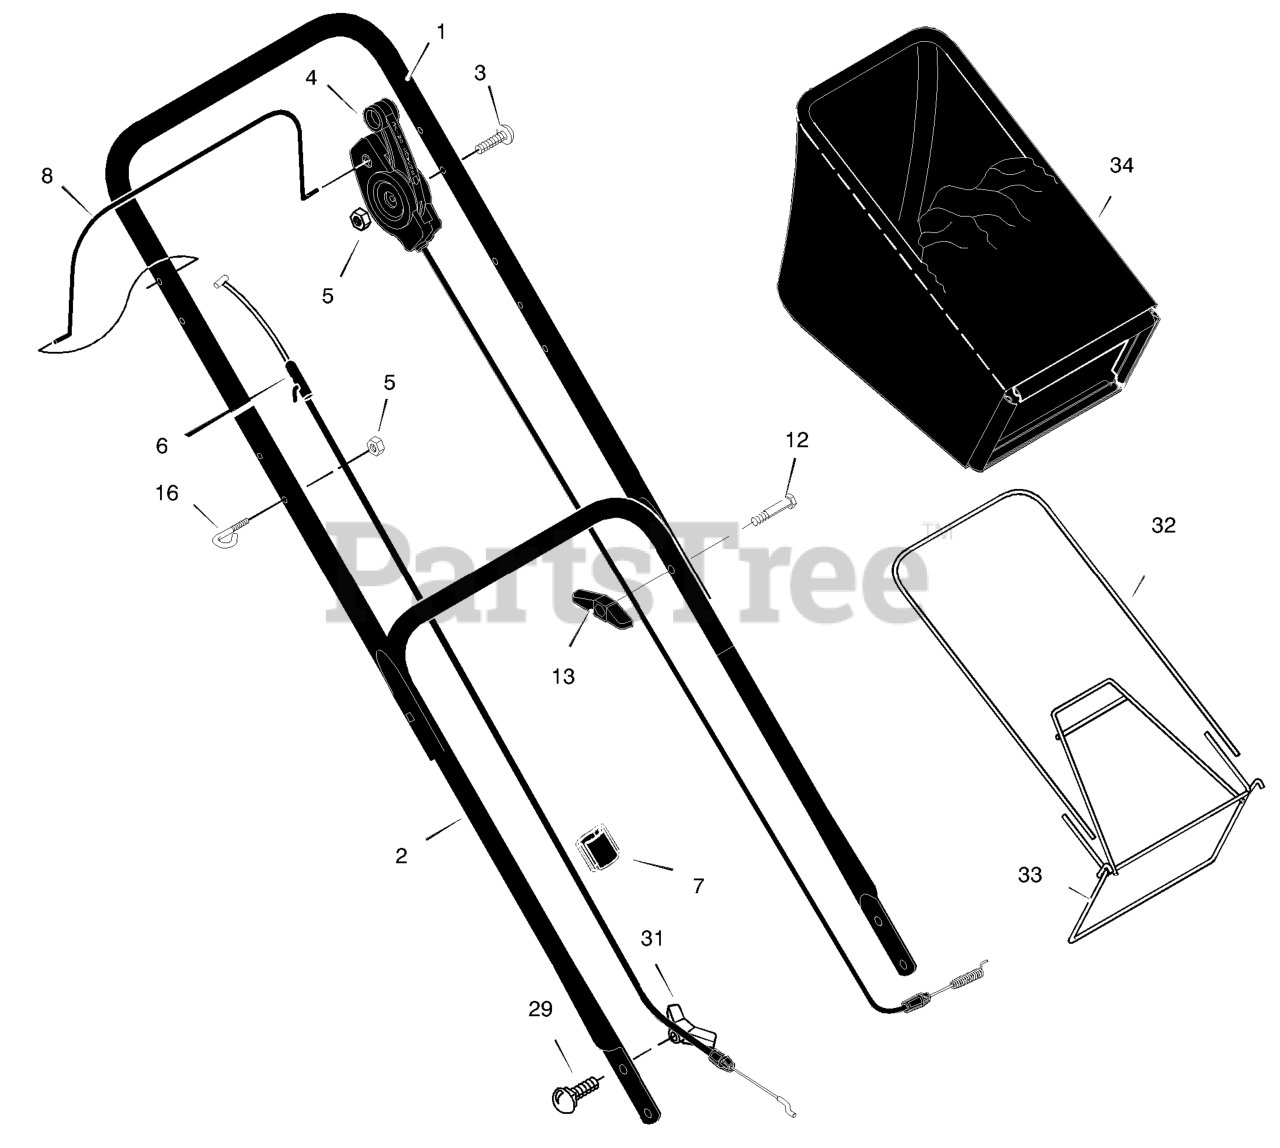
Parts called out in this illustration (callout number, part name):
1	Handle, Upper (Black)
2	Handle, Lower (Black)
4	Control, Drive
5	Locknut
6	Cable, Stop (Briggs)
7	Fastener, Double Cable
8	Lever, Stop
13	Knob
16	Guide, Rope
29	Bolt, Carriage
31	Knob, Plastic
32	Tube, Bag
33	Frame Assembly
34	Bag, Cloth
